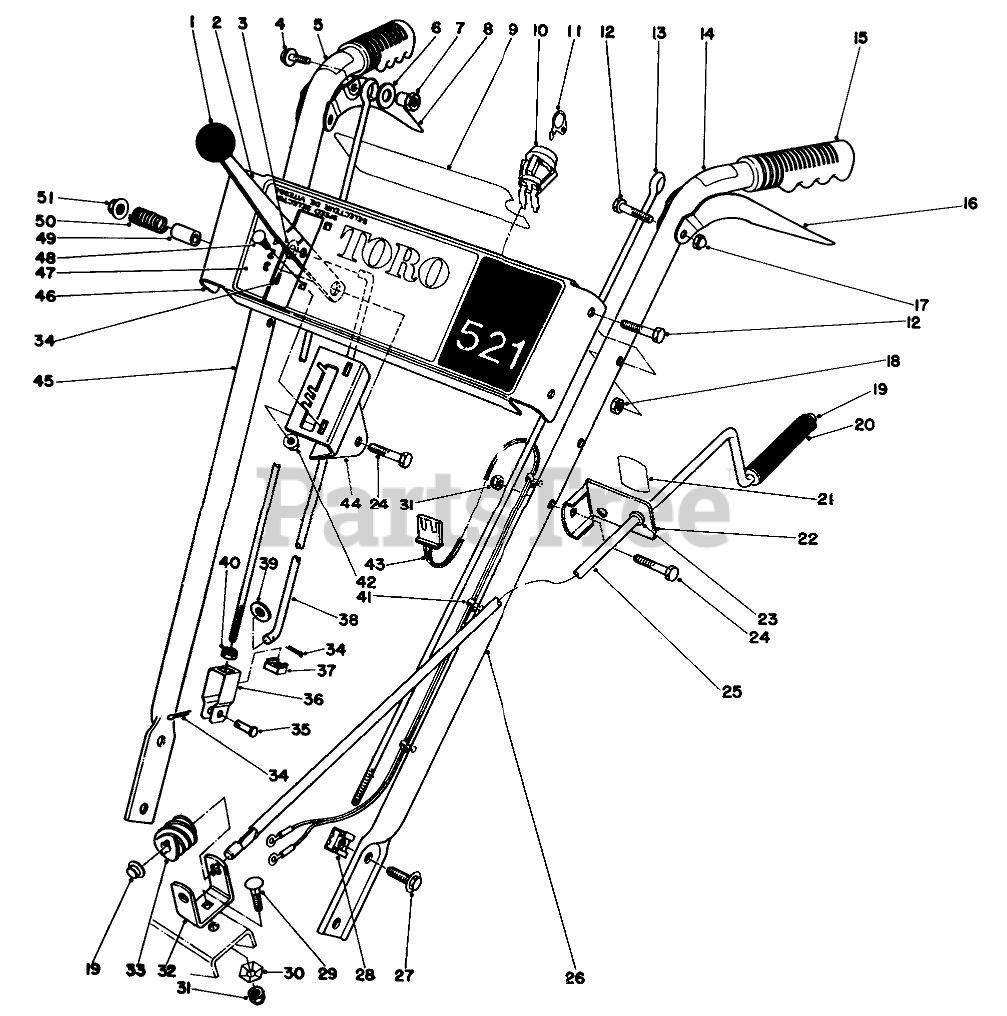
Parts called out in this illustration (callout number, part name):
2	SPEED SELECTOR B
3	WASHER-FLAT
4	SCREW-HHF
5	Decal-Auger Drive
6	WASHER-FLAT
7	POST-MOUNTING, LINKAGE
8	Lever-Auger Control
9	Decal-Escutcheon Back
10	SWITCH
11	Key
12	SCREW-HH
14	Decal-Wheel Drive
15	Grip
16	Lever-Traction Control
17	NUT-CAP
18	NUT-LOCK, CONE
19	RETAINER-PUSH ON
20	GRIP-CONTROL, CHUTE
21	CHUTE DECAL
22	Bracket-Chute Control Mounting (Incl. Ref. #21 & 23)
23	Bushing
24	SCREW-HH
25	ROD-CONTROL, CHUTE
26	Handle Left
27	SCREW-HHF
29	BOLT-CARR
30	WASHER-LOCK
31	NUT-LOCK, NI
32	BRACKET-WORM
33	GEAR-WORM, CHUTE
34	SCREW-HSH
35	PIN-CLEVIS
36	CLEVIS
37	NUT-RETAINED
38	ROD-SELECTOR, SPEED
39	WASHER-PLAIN
40	NUT-JAM
41	Mount-Wire
42	NUT-HHF
43	WIRE HARNESS
44	Mount-Speed Selector
45	Handle Ring
46	ESCUTCHEON PLT B
47	ESCUTCHEON DECAL 521
48	SCREW-CARRIAGE
49	SPACER
50	SPRING
51	NUT-HF
